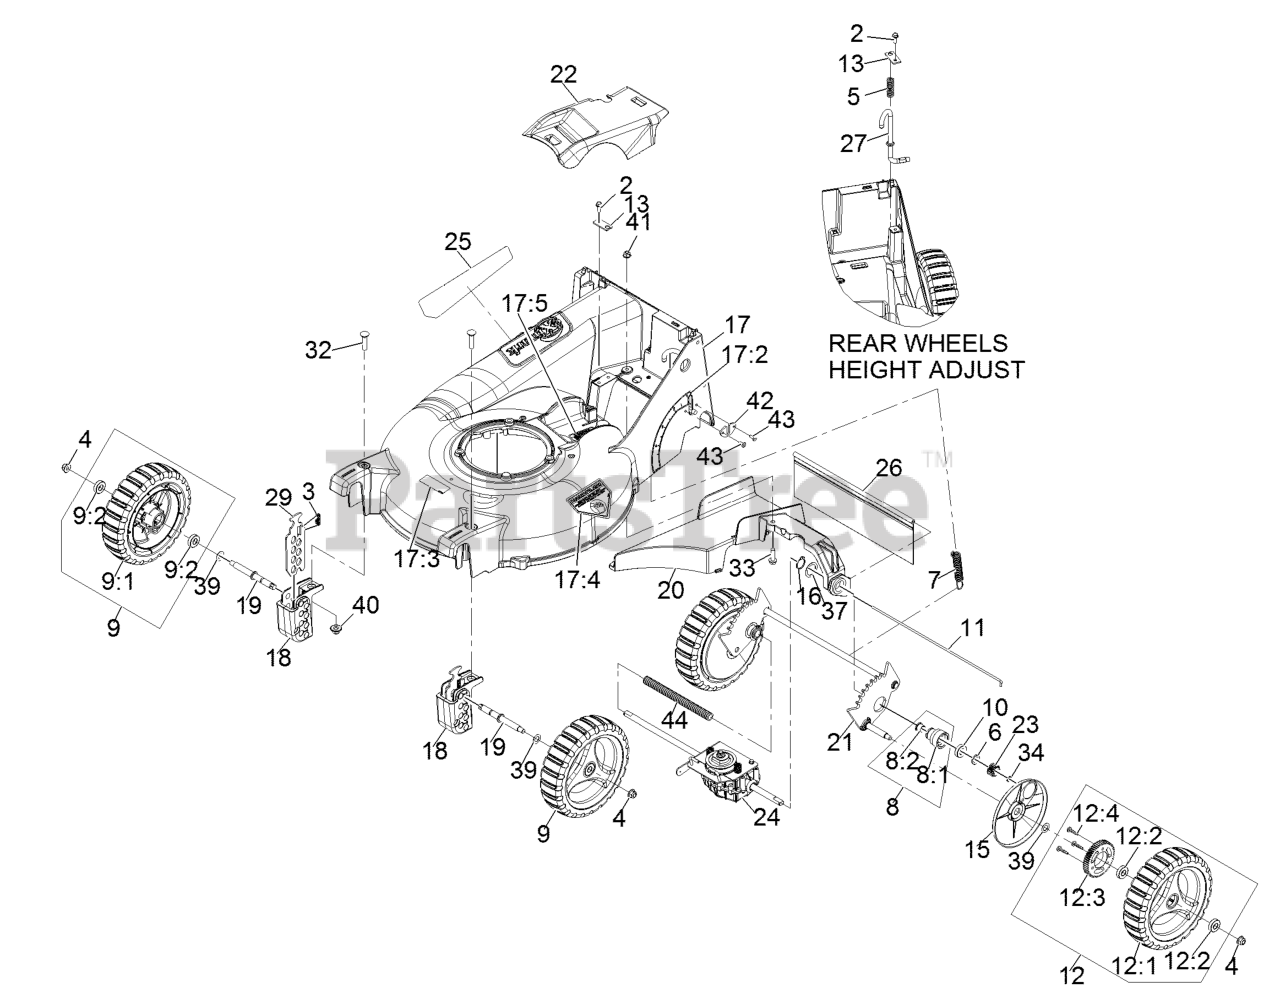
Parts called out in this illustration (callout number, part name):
2	SCREW-HWH
3	SPRING-COMPRESSION
4	NUT-HF, NI
5	SPRING-COMPRESSION
6	SPACER-BUSHING
7	SPRING-EXTENSION
8	HOUSING ASM
8:1	HOUSING-BEARING
8:2	BEARING-FLANGE
9:2	BEARING-BALL
10	BEARING-BALL
11	ROD,SHIELD
12:2	BEARING-BALL
12:4	SCREW-DRIVE
13	BRACKET,MOUNT
15	COVER,GEAR
16	RING-RETAINING
17	DECK W/DECALS
17:2	DECAL-HEIGHT OF CUT
17:3	DECAL-BLADE
17:4	DECAL-DANGER
17:5	DECAL-COVER MISSING
18	BLOCK,FRONT QUADRANT
19	AXLE-WHEEL
21	WLD,REAR AXLE P21
22	COVER,BELT
24	ASM,TRANSMISSION W/BRACKE
25	DECAL-COMM 21 S-SERIES
26	SHIELD-TRAILING P21
27	ROD-HEIGHT ADJ P21
29	PLATE, FRONT HEIGHT
32	SCREW-CARR
33	SCREW-HWHTF
34	RING-RETAINING
39	WASHER-PLAIN
40	Nut-Nyloc 3/8-16 Flg
41	NUT-HF, NI
42	PLATE,WEAR
43	RIVET-BLIND
44	COVER-SHAFT, DRIVE
